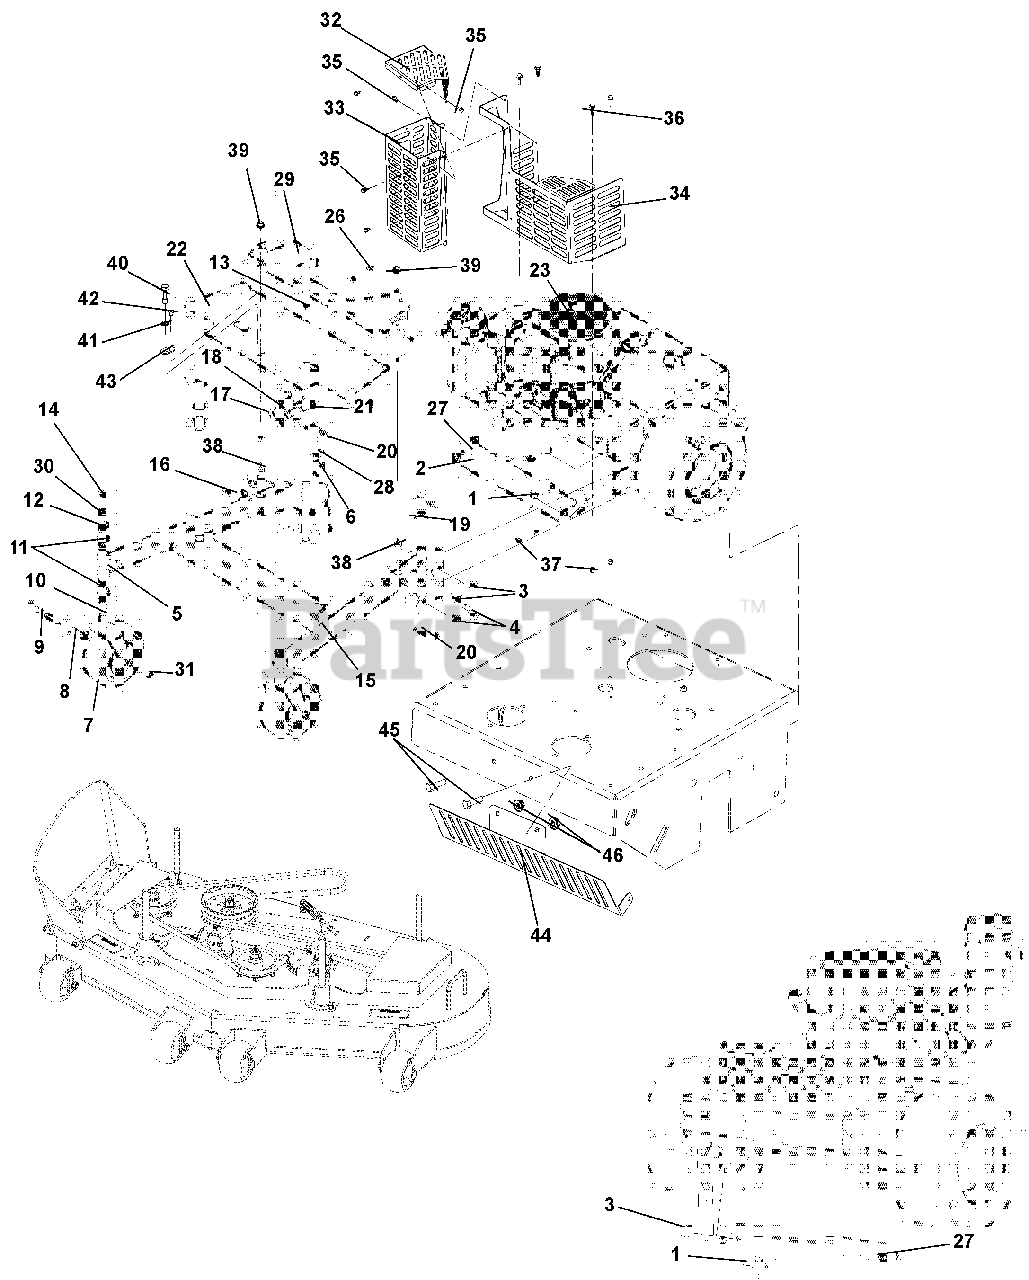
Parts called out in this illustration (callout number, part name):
1	LOCKNUT, 1/2-13 NYLOC Y
2	PLATE, ENGINE BED FRONT (988324, 988325)
2	PLATE ,ENGINE BED FRONT (988323)
3	BOLT, 1/2-13 X 1.25 HEX 5 Y
4	BOLT, 1/2-13 X 1.50 HEX 5 Y
5	FTG, 1/4-28 STRGT GREASE ZERK
6	BSHG, FLG 1.00 X 1.25 X 1.50 X 1.50 EP REV
7	9X3.5-4 CAREFREE BLT TOGETHER
8	TUBE, CASTER AXLE
9	BOLT, .50-13 X 5.50 HEX 5 Y
10	WLDT, FRONT WHEEL FLOAT WALK
11	BRG, FLG 1.00X1.25X1.00
12	WSH-FL-ST .38 X 1.50 X .125 REV
13	BOLT, HEX .25-20 x .75 GR5
14	BOLT, .38-16 X 1.25 HEX 5 Y
15	WLDT, DECK FRAME 52 FLWLK (988325)
15	WLDT, DECK FRAME 48 FLWLK (988324)
15	WLDT, DECK FRAME 36 FLWLK (988323)
16	BUMPER GROMMET .125 X .25 REV
17	WASHER, .905 X 1.750X.250
18	WASHER, FLAT .630 x 1.50 x .25
19	WASHER, FLAT-STEEL .688 X 1.75 X.134 REV
20	PIN, HAIR-INTERNAL .17 X .68 X 3.50 REV B
21	BOLT, 5/8-11 X 1.50 HEX 8 Y
22	SHIELD, BELT 52" HYDRO WALK (988325)
22	SHIELD, BELT 48" MAIN (988324)
22	SHIELD, BELT 36 MAIN (988323)
23	CABLE TIE, .15 X 8.50
24	SWIVEL, 3/8-24
25	WASHER, .406 X .813 X .065 FLAT Y
26	NUT, LOCK NYLON .250-20
27	PLATE, ENGINE BED REAR (988324, 988325)
27	PLATE, ENGINE BED REAR (988323)
28	WASHER, FL-STL REV
29	SHIELD, BELT 36" (988323)
29	SHIELD, BELT 48" (988324)
29	SHIELD, BELT 52 PROWALK (988325)
30	WSHR-LK .38X.094 REG YWZC
31	NUT-LK-NYL-FLG .50-13 YWZC
32	GUARD, EXHAUST
33	GUARD, UPPER EXHAUST
34	GUARD, EXHAUST
35	SCR-TAP .25-20X.50 HWH YWZ
36	BLT-HEX .25-20X.75 GR5 YWZC
37	NUT-LK NYL .25-20 YWZC
38	BUMPER, RUBBER
39	NUT-SPNLK-FLG .312-18 YWZC
40	BLT, HEX 0.38-16 X 1.25 GR5 CAPTIVE
41	LOCK, WSHR-EXT 0.391 X 0.628 X 0.036 YWZC
42	RVT-POP .187x.250 (#64) YWZC
43	KEEPER, BOLT
44	BRKT, REAR BUMPER
45	BLT, HEX .38-16X1.00 GR5 YWZC
46	NUT, SPNLK-FLG .375-16 YWZC
